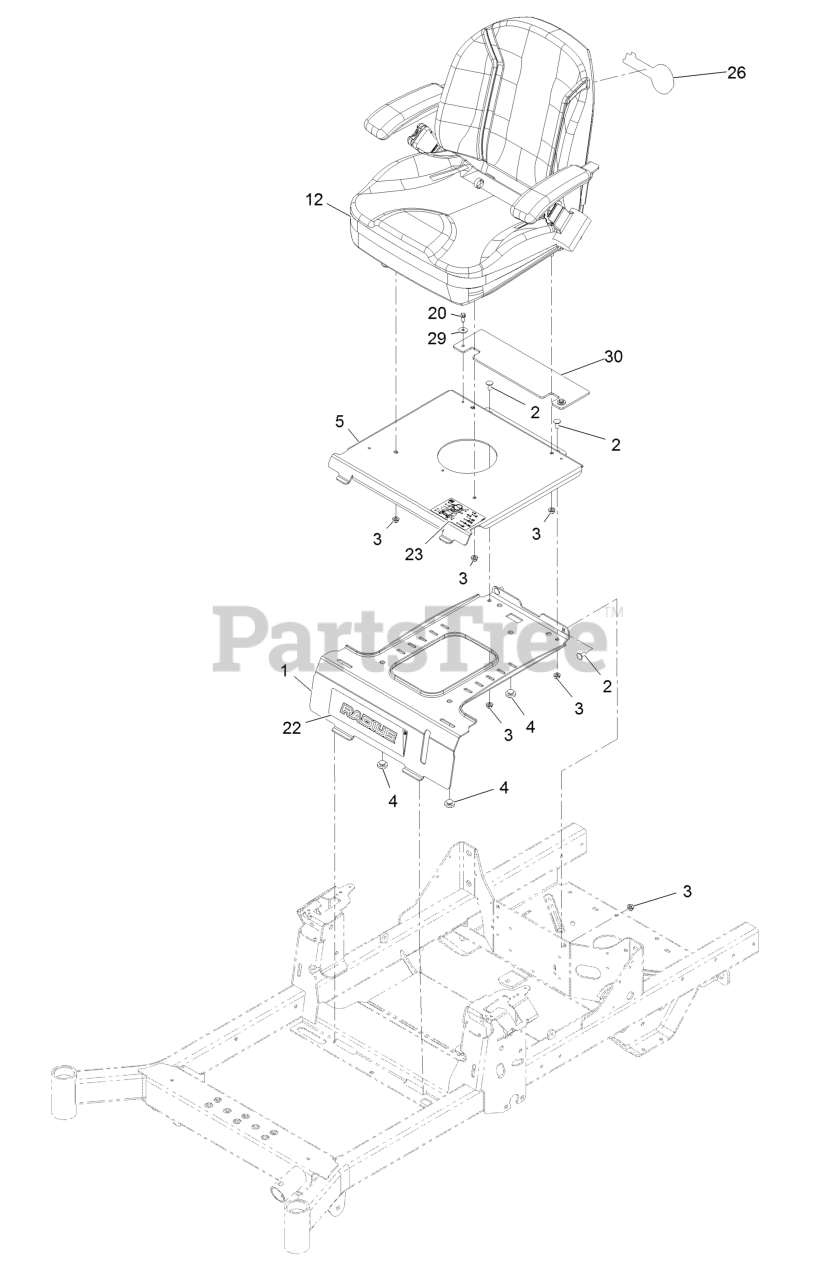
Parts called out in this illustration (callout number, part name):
1	Plate-Retainer, Tank
2	Bolt-Carriage 5/16-18 X 3/4 Short Neck
3	Nut-Nyloc 5/16-18 Flg
4	Bumper-Seat
5	Plate-Seat, Fixed
12	ASM-Seat Exmark
20	Screw-HWH 1/4-20 X 3/4
22	Decal-Radius Logo
23	Decal-Aid, Service
26	Decal-Exmark Logo
30	Guard, Rubber
